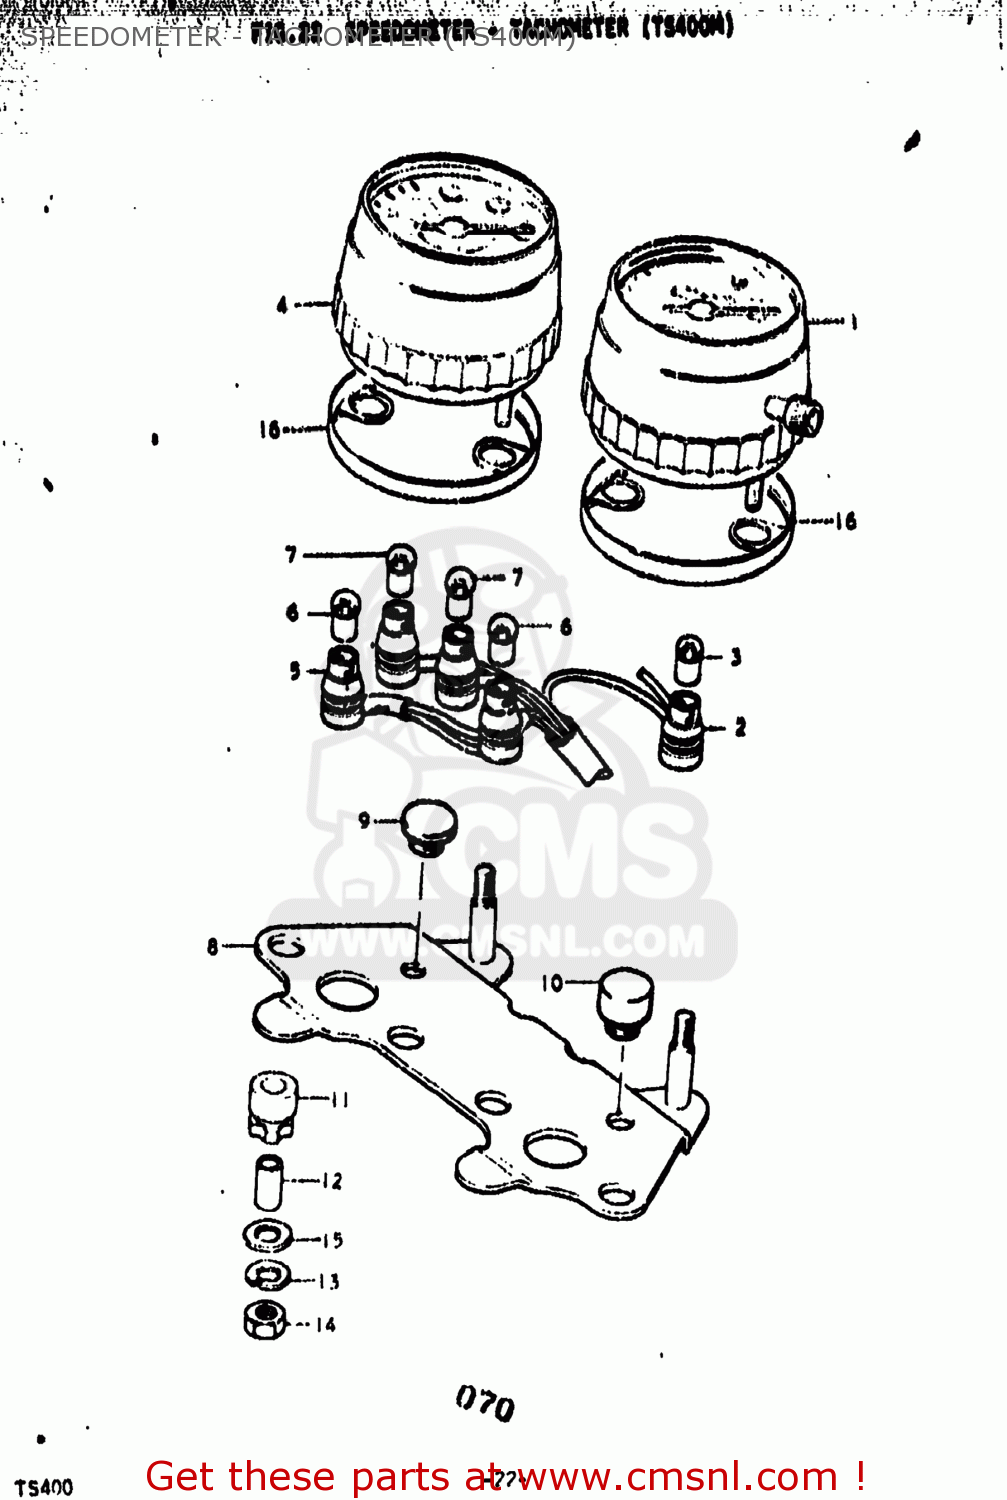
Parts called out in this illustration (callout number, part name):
1	SPEEDOMETER ASSEMBLY
2	SOCKET,METER
3	BULB(12V3.4W,STANLEY,A72A)
4	TACHOMETER
5	SOCKET,METER
6	BULB(12V3.4W,STANLEY,A72A)
7	BULB(12V1.7W,A71A)
8	BRACKET,METER
9	CUSHION,METER
10	CUSHION,METER
11	CUSHION,METER NO.1
12	SPACER,METER
13	LOCK WASHER
14	NUT
15	WASHER
16	BRACKET,SPEEDOMETER
